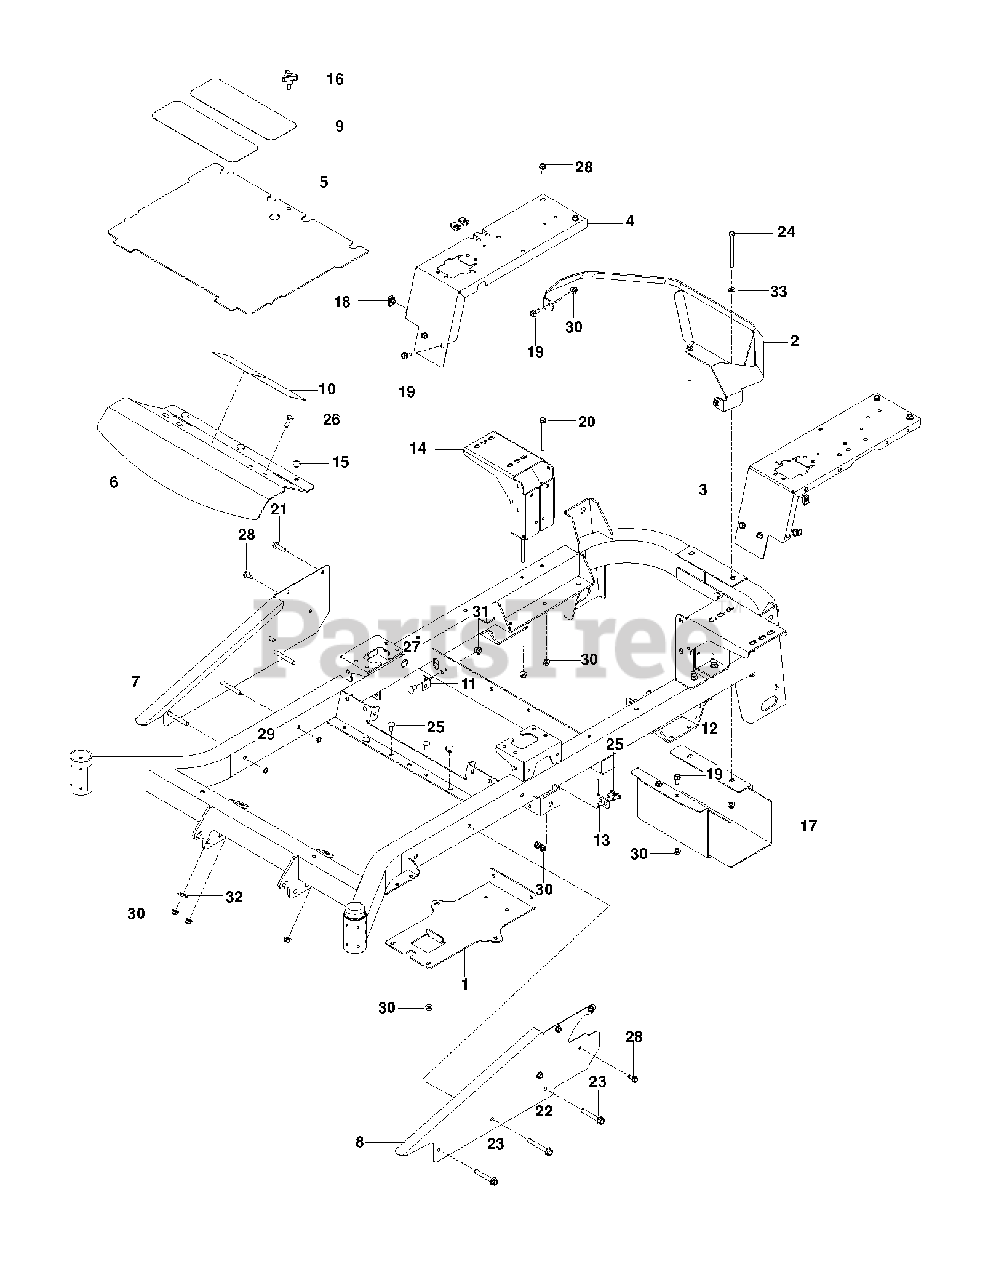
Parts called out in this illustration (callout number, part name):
1	PLATE, BATTERY, BLACK
2	GUARD, REAR MZ, GRAY
3	PANEL.FILLER.LT.ORANGE
4	PANEL.FILLER.RT.ORANGE
5	PLATE, FLOOR W/DECALS
6	PLATE, FOOTREST
7	SIDE.RT.ORANGE
8	SIDE.LT.ORANGE
9	ANTI-SKID PAD
11	BRACKET.DAMPENER.BLACK
12	SHIELD.MUFFLER.BLACK
13	STOP, DECK, EZ+
14	MOUNT, TANK, ZT BLK
15	GROMMET, BUMPER
16	KNOB W/STUD
17	HEAT SHIELD
18	U-CLIP 5/16-18 NUT RETAINER
19	HHFS 5/16-18 X 3/4
20	HHFS 5/16-18 X 3 3/4
21	HHFS 5/16-18 X 1.25 TPBLT GD 5
22	HHFS 3/8-16 X 2 3/4
23	HHFS 3/8-16 X 2.5 GR 5 ZD
24	HCS 5/16C X 4
25	BOLT 5/16C X 3/4" CARRIAGE
26	RHSNB 5/16C X 1
27	RHSNB 3/8-16 X 3/4 GR 5 BLK ZN
28	BOLT 5/16-18 X 3/4
29	NUT HEX 3/8-16 NYLON, THIN
30	5/16-18 NYLOC FLANGE NUT
31	NUT 3/8-16 HEX FLG NYLOC ZD
32	WASHER 1/2" FLAT
33	FLAT WASHER 5/16 SAE
